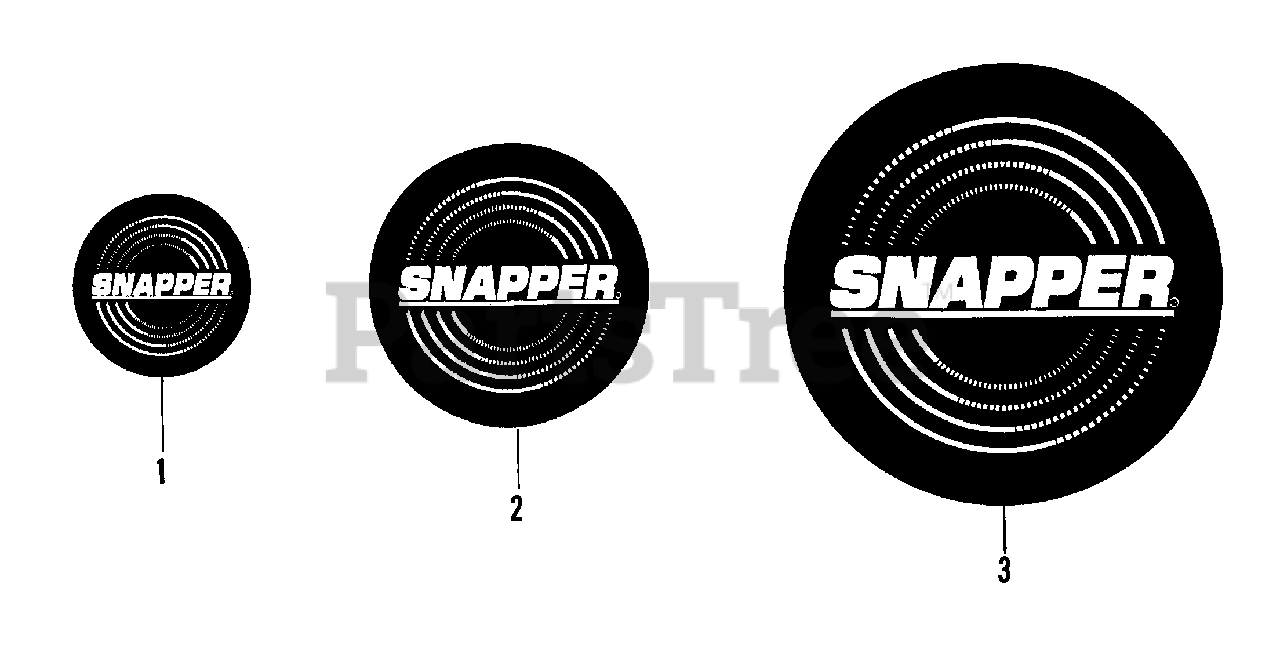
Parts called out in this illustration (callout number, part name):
1	DECAL, 1.8 Dia. Good
2	DECAL, 2.50 Dia. Better
3	DECAL, 3.38 Dia. Snapper
